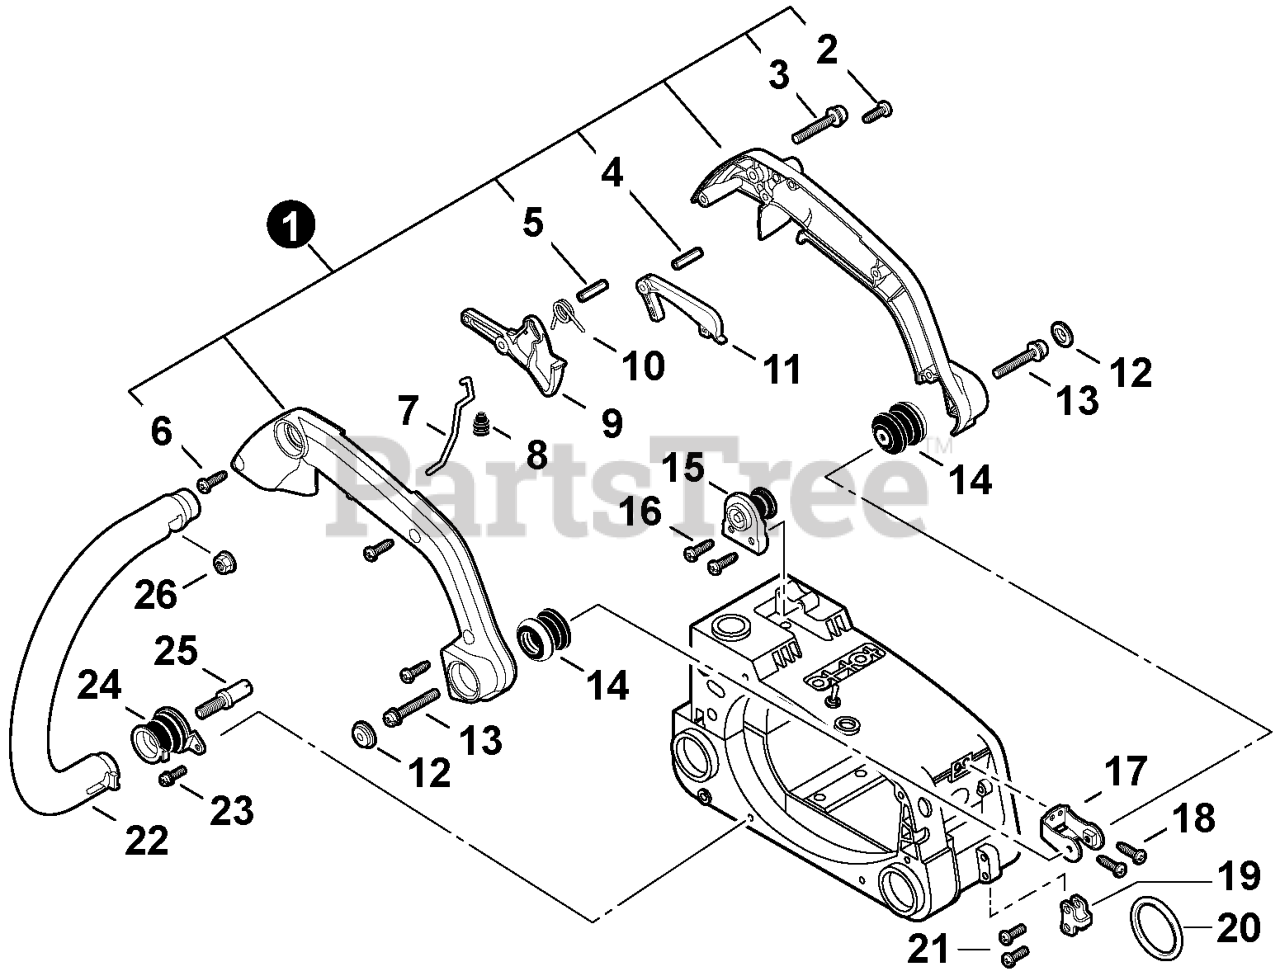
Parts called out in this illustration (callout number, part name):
1	HANDLE SET, REAR
2	SCREW 5x14
3	SCREW 5x35
4	PIN, SPRING 4x20
5	PIN, SPRING 4x25 SUS
6	SCREW 4x16
7	ROD, THROTTLE
8	GROMMET, THROTTLE ROD
9	TRIGGER, THROTTLE
10	SPRING, TORSION
11	LOCKOUT, THROTTLE
12	CAP, CUSHION
13	SCREW 4x10
14	CUSHION 4
15	CUSHION 5
16	SCREW 4x14
17	BRACKET, HANDLE
18	SCREW 4x14
19	BRACKET, HARNESS
20	RING, HARNESS 32
21	SCREW 4x16
22	HANDLE, FRONT
23	SCREW 4x16
24	CUSHION 5
26	NUT, FLANGE M5
